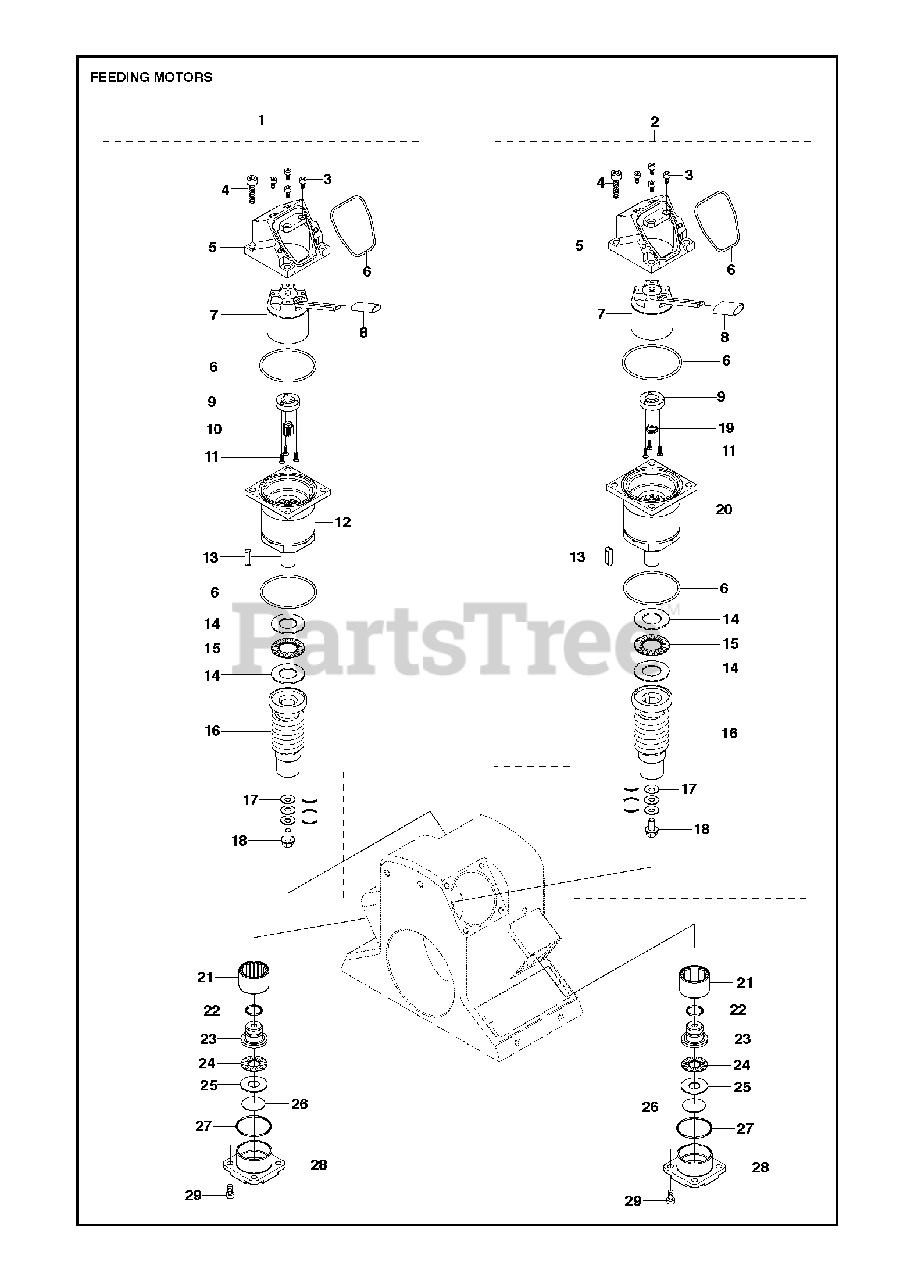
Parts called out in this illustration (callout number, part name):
1	MOTOR ASSYIncl. 3 - 18
2	MOTOR ASSYIncl. 3-9,11,13-18, 19-20
16	AUTOMATIC FEEDING SYSTEM
